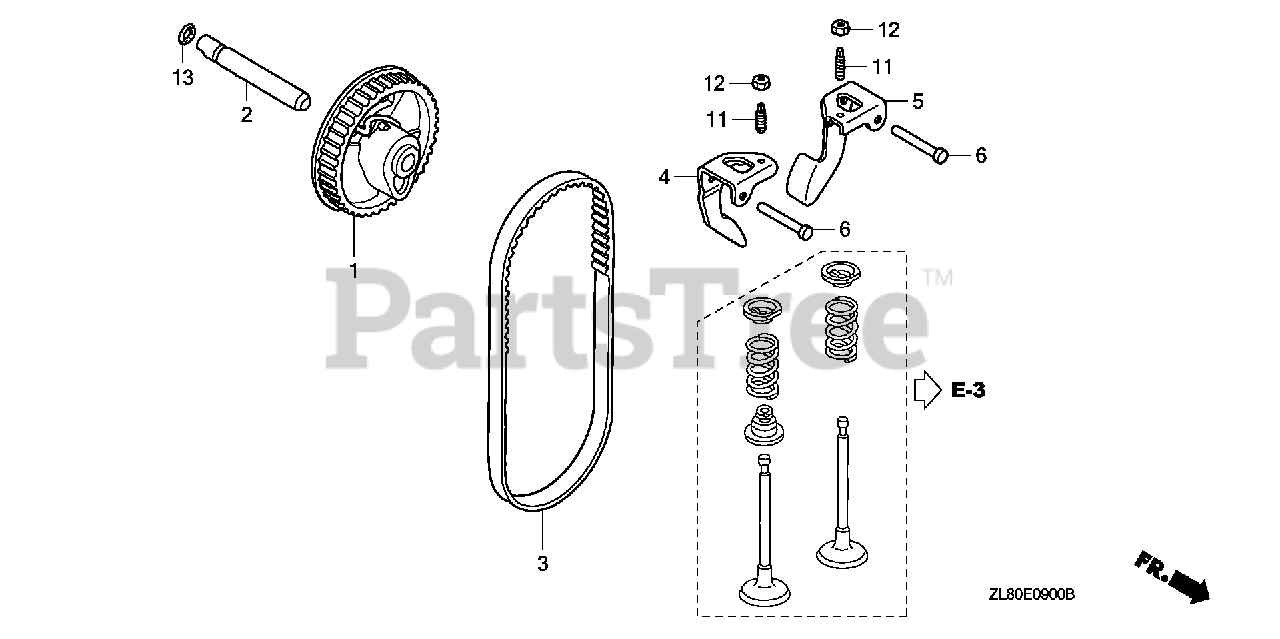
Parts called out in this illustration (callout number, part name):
1	PULLEY, CAMSHAFT
2	SHAFT, CAM PULLEY
3	BELT, TIMING (84HU7 G-200)
3	BELT, TIMING (84HU6 G-200)
4	ARM, IN. VALVE ROCKER
5	ARM, EX. VALVE ROCKER
6	SHAFT, ROCKER ARM
11	SCREW, TAPPET ADJ.
12	NUT, TAPPET ADJ.
13	O-RING (6.8X1.9) (ARAI)
